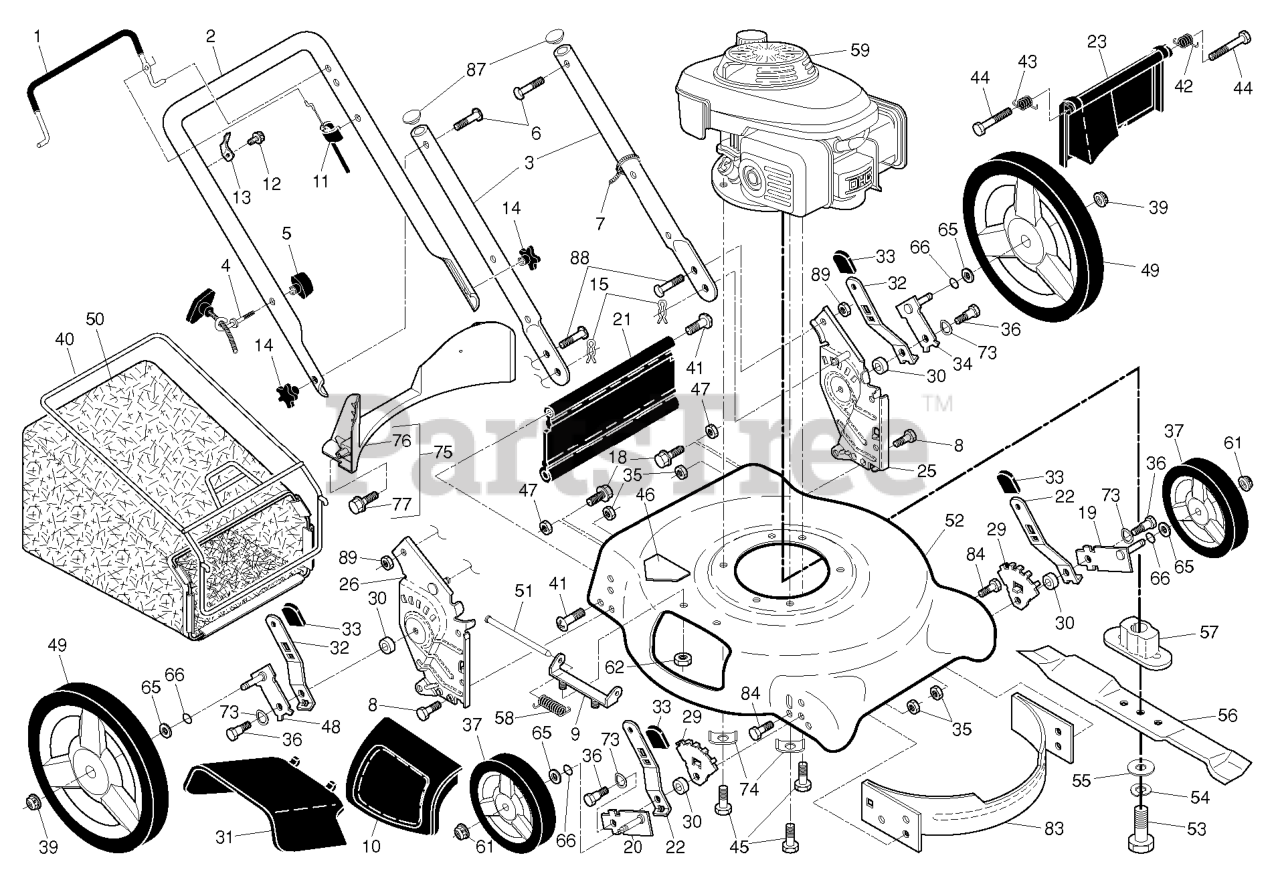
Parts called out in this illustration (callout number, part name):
2	SQUARE KEY
15	WASHER PLAIN WASHER 3/8 X 0.08
17	SPRING.BRAKE.K46.GREEN
26	SPRING.RETURN.CRUISE
29	ROD.BRAKE.K46
35	ROD ROD.PARKINGBRAKE.GT.HUSQ/P
37	WASHER.HARDENED
42	PEDAL COVER
50	IDLER.FLAT.910.OFFSET
51	NUT LOCK FLG 3/8-16 UNC
52	IDLER.V-GROOVE.910.OFFSET
64	SHAFT.ASM.PEDAL.BRK.CNTR
69	HAIRPIN.SOFT.ZINC.059X1.125
99	ARM.PIVOTING.TCRD.GEN2.5.BAGGE
125	SCREW
153	RETAINER M
161	SPRING, RETURN LT
166	NUT.PUSH.625
167	LATCH.BRAKE.SPRING
170	KEEPER.V-IDLER.CENTER.
177	PIN COTTER;LOCKING;BOWTIE;1IN
183	SPACER AXLE
184	HANDLE.PARKING.BRAKE.H (BLK)
186	SPACER.RETAINER
188	LINK.CLUTCH.GROUND DRIVE.LONG
189	BELLCRANK.GROUND.DRIVE.TEX.
190	KEEPER.BELLCRANK.DRIVE
206	BRACKET.MOUNT.CRUISE.LATCH
209	ROD ROD.CRUISECONTROL.GT.HUSQ/
210	ROCKER.ASM.PEDAL.CONTR
211	BEARING.NYLON
213	KNOB.CONTROL.CRUSIE.HU
214	PEDAL.FORWARD.PAD.TEX
215	PEDAL.COVER.REVERSE.CRD.X428BK
216	BRACKET.PULLEY.IDLER.W/TEX
221	RETAINER.SPRING.CLIP.H
222	WASHER 21/32 X 1-1/4 X 10 GA.
225	KEEPER.BELT.TRANSAXLE.K46
325	BRACKET.TRQ.STP.46.20".TIRE.LH
326	BRCKT.PNT.TRQ.STP.46.20TIRE.RH
